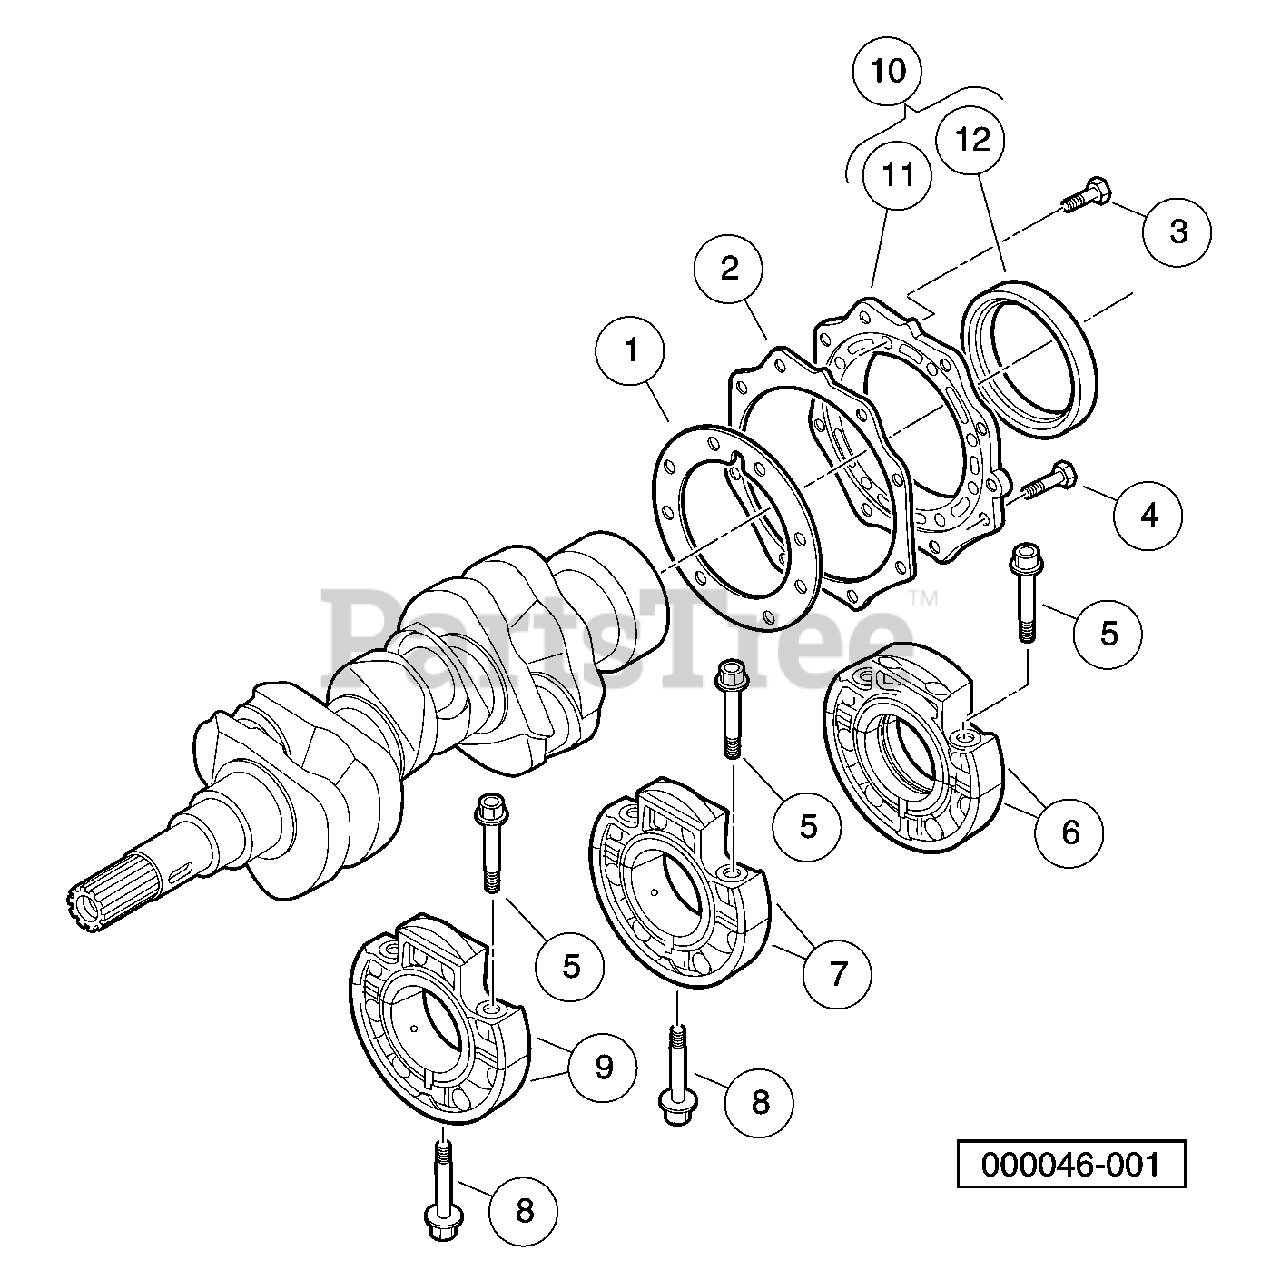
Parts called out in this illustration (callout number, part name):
1	Gasket, Bearing Case
2	Gasket, Cover.
3	Bolt, M6 X 1 X 20
4	Bolt, M6 X 1 X 22
5	Bolt, Bearing Case, Top
6	Assy Case, Main Brg, First
7	Assy Case, Main Brg, Sec
8	Bolt, Bearing Case, Bottom
9	Assy Case, Main Brg, Third
10	Assy, Cover, Bearing Case
11	Cover, Bearing Case
12	Seal, Oil.
